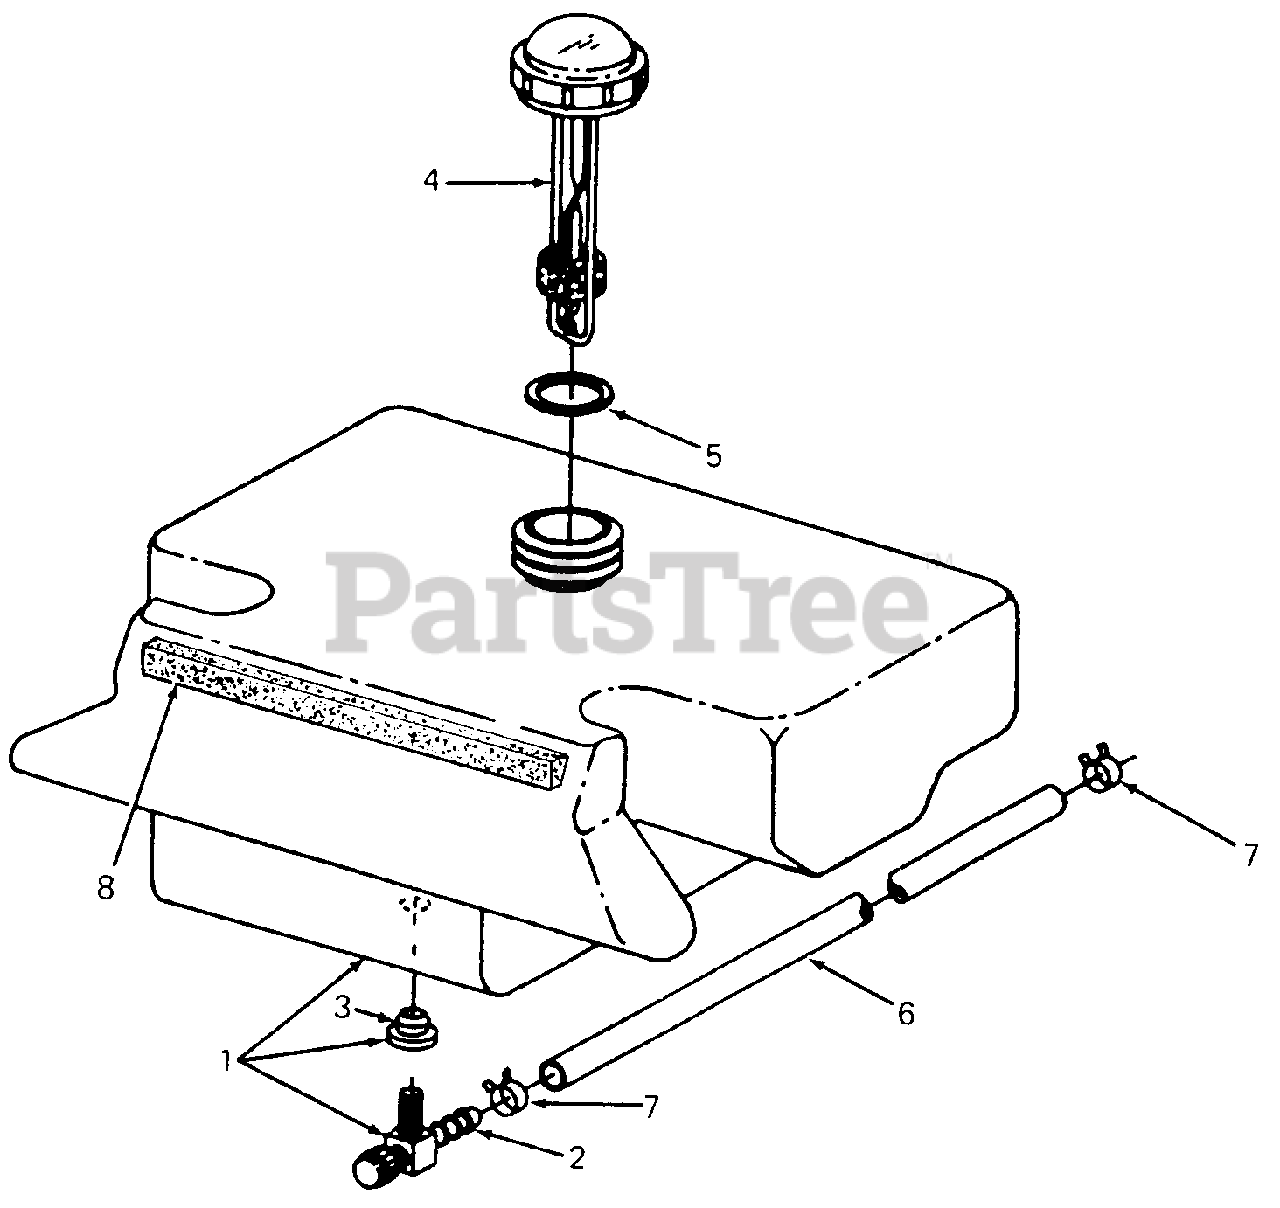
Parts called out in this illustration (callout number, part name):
1	Tank Assy, Fuel
2	Valve w/Screen, Shut-off
3	Bushing
4	Cap w/Gauge, Fuel
5	Gasket, Fuel Tank Cap
6	Line, Fuel Tank to Filter, 56 in. Lg
7	Clamp, Tube Hose, 1/2 OD
8	Strip, Foam Gasket Sealing, 12 in. Lg
